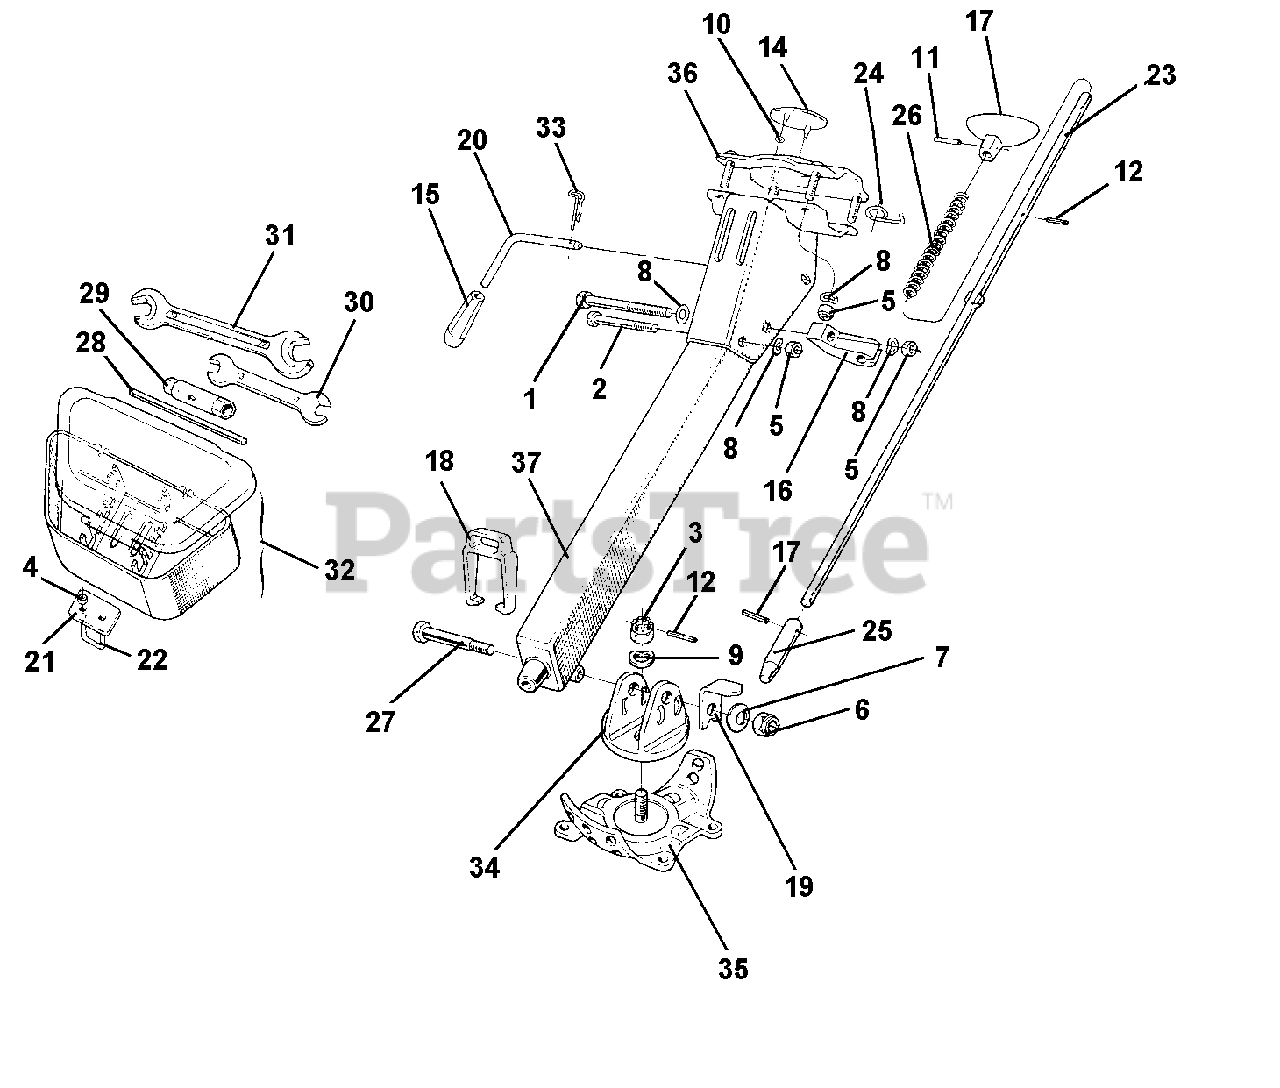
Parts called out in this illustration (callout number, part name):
1	SCREW TE M8 X 100
2	SCREW M8 X 60
3	NUT, HEX INT M12 UNI 5593 6S
4	NUT, SELF LOCKING M6
5	NUT, SELF LOCKING M8
6	NUT, SELF LOCKING M12 LOW
7	CONICAL WASHER
8	WASHER, LOCK 8.4
9	WASHER, LOCK 13
10	WASHER, LOCK FOR PINS
11	LOCKING PIN 4 X 20 SPIRAL
12	PIN, LOCKING SW 3 X 22
13	LOCKING PIN SPIRAL
16	SUPPORT CONTROL ROD CUT
18	PASSAGE FOR SHEATH
19	LOCKING PLATE
20	LEVER FOR SECTOR
24	SHEATH HOOK
27	SCREW SPECIAL M12 X 70
28	PARALLEL PIN D 7 X 130
29	TUBE KEY 10 - 13
30	OPEN KEY 13 - 17
31	OPEN KEY 19 - 22
32	NEUTRAL TOOL BOX
35	CAP WITH HOLE D. 13
37	HANDLEBAR STEERING COLUMN
